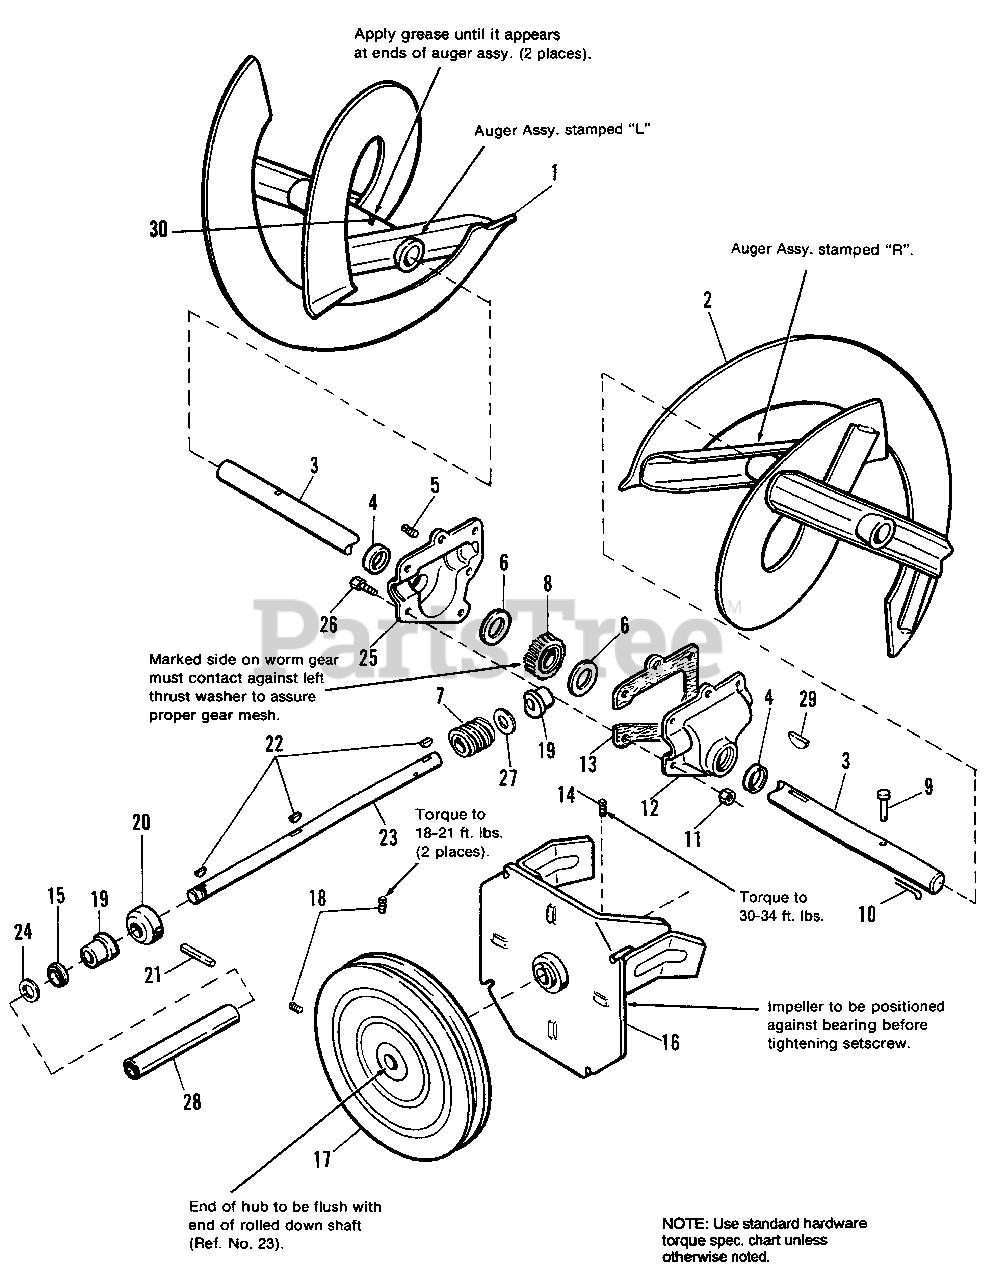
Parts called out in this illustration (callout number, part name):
1	AUGER ASSY., L.H., (24")
2	AUGER ASSY., R.H., (24")
3	SHAFT, Auger
5	PLUG, Pipe, Tapered, 1/8
6	WASHER, Thrust
7	GEAR, Rolled Worm
8	GEAR, Worm
9	PIN, Shear
10	PIN, Cotter, 3/32 x 3/4
11	LOCKNUT, Hex, 1/4-20
12	CASE, Gear, R.H.
14	SETSCREW, Sq. Hd., 3/8-16 x 1/2
16	Impeller ASSY.
17	PULLEY, Auger Input
18	SETSCREW, Sq. Hd., 5/16-18 x 1/2
19	BUSHING, Flange
20	COLLAR, Thrust
21	PIN, "Drive Lok" Type A, 3/16 x 1-1/2
22	KEY, Woodruff, 3/16 x 5/8
23	SHAFT, Worm
24	WASHER
25	CASE, Gear, L.H.
26	CAPSCREW, Hex Hd., 1/4 20 x 7/8
27	WASHER, Thrust
28	TUBE, Worm Shaft
29	KEY, Woodruff, 1/4 x 3/4
30	GREASE FITTING
